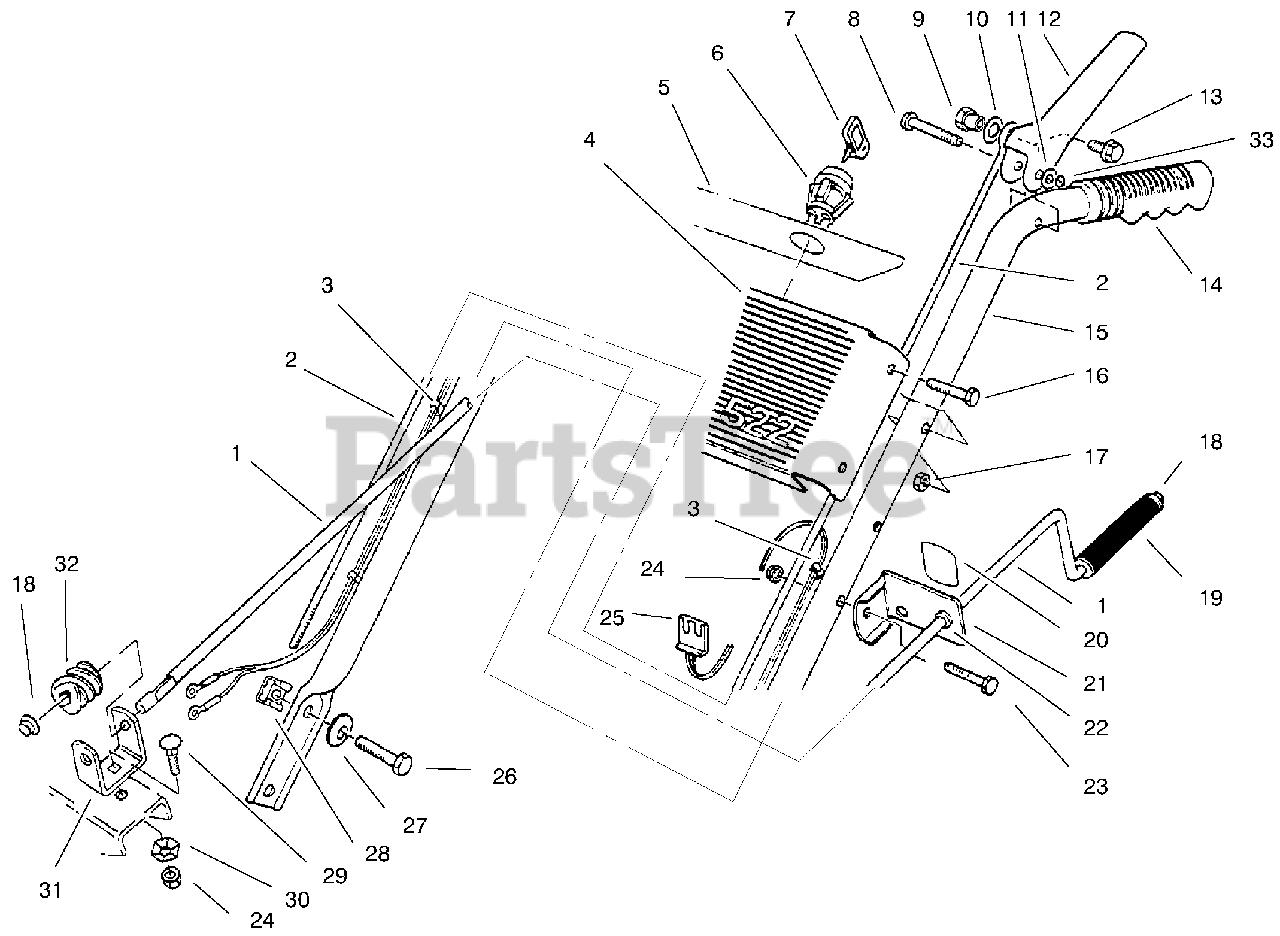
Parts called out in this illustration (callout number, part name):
1	Rod-Chute Control
2	Link-Upper
3	Mount-Wire
4	Panel-Escutcheon
5	Decal-Escutcheon Back
6	Switch-On/Off
7	Key-Ignition
8	Pin-Control Lever
9	Post-Linkage Mounting
12	Handle-Control
13	Screw-Hex. Flange Hd.
14	Grip-Handle
15	Handle-Left
16	Screw-Hex. Head
17	Nut-Lock
19	Grip-Rod
20	Decal-Chute Direction
21	Bracket-Chute Control (Incl. Ref.# 20 & 22)
22	Nyliner
23	Screw-Hex. Hd.
24	Nut-Lock
25	Wire Harness Asm. (Incl. Ref.# 3)
26	Screw-Hex. Hd.
27	Washer-Belleville
28	Retainer-Nut
29	Bolt-Carriage
30	Washer-Pyramidal
31	Bracket-Chute Worm
32	Gear-Worm
33	Ring Clip
